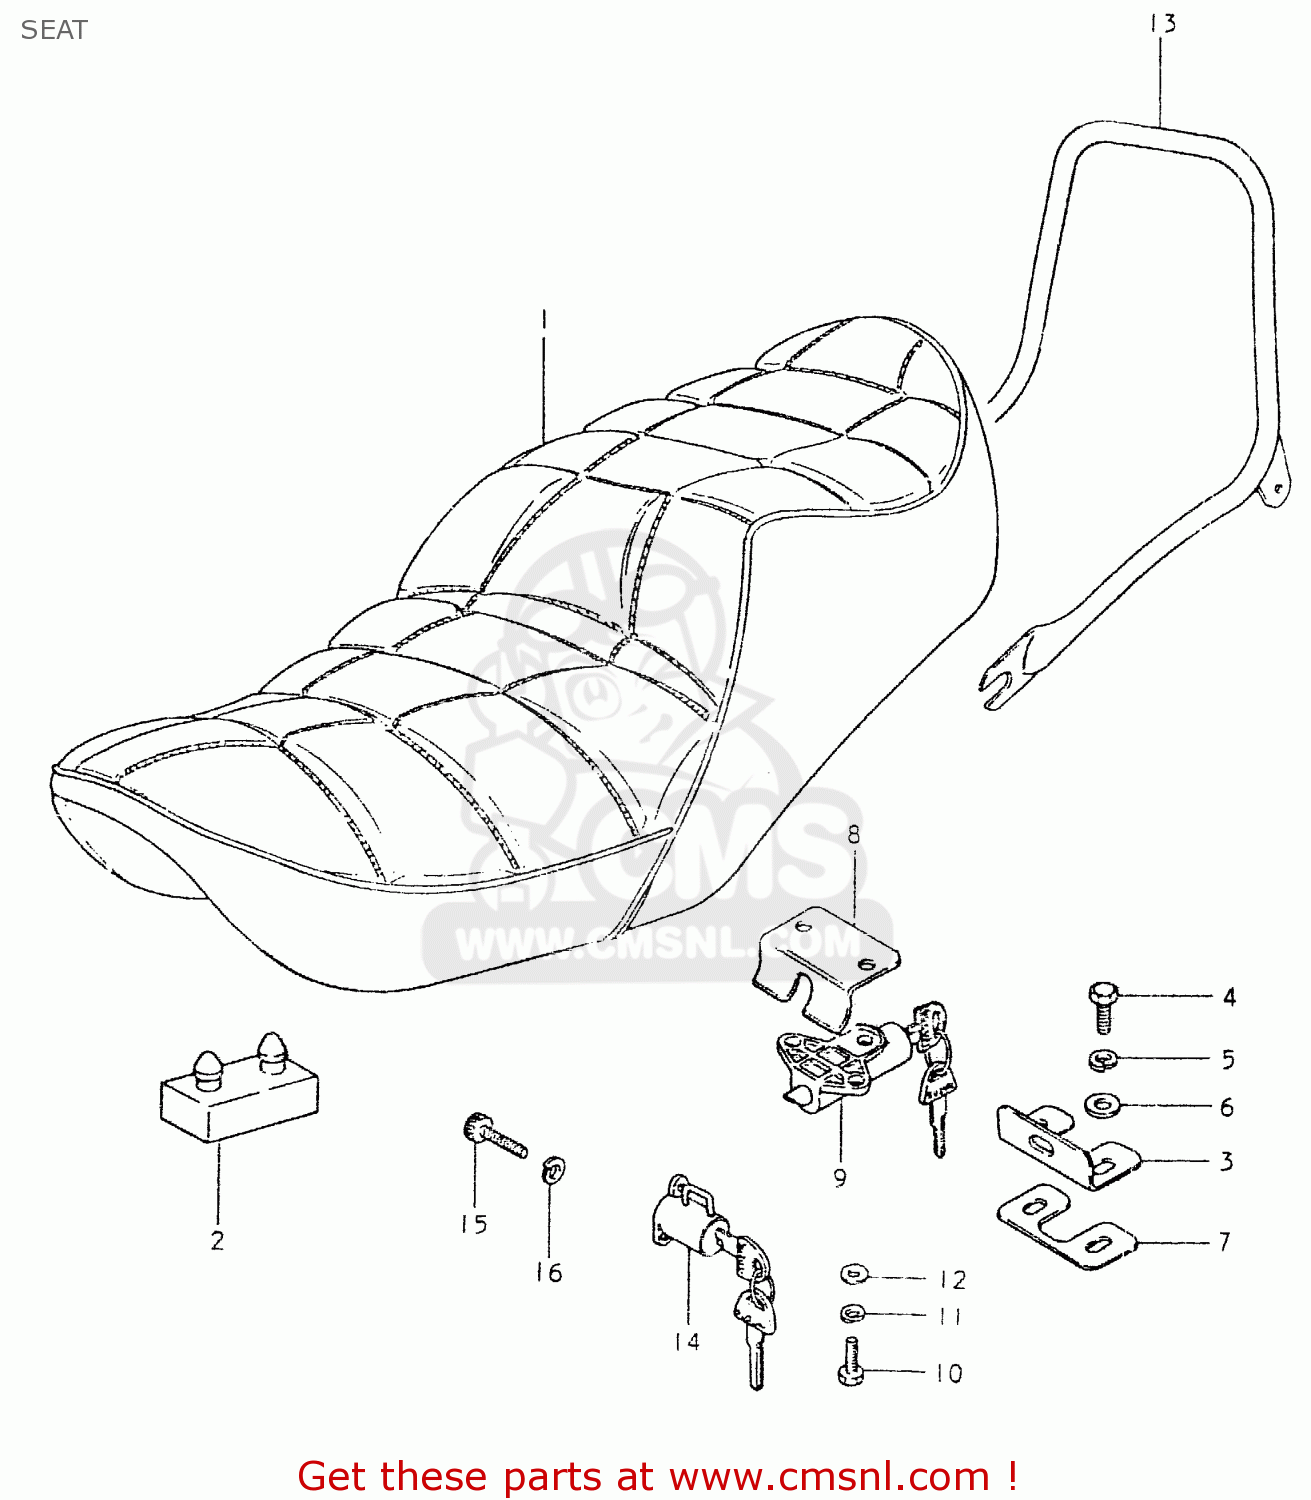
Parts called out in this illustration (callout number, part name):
1	SEAT (BLACK)
2	CUSHION
3	STRIKER,SEAT LOCK
4	BOLT, UPPER
5	LOCK WASHER
6	WASHER 6MM
7	SHIM,SEAT LOCK STRIKER
8	PLATE,SEAT LOCK
9	LOCK ASSEMBLY,SEAT
10	BOLT
11	LOCK WASHER
12	WASHER 6MM
13	HANDLE,PILLION RIDER
14	LOCK ASSEMBLY,HELMET
15	BOLT 6X11
16	LOCK WASHER
